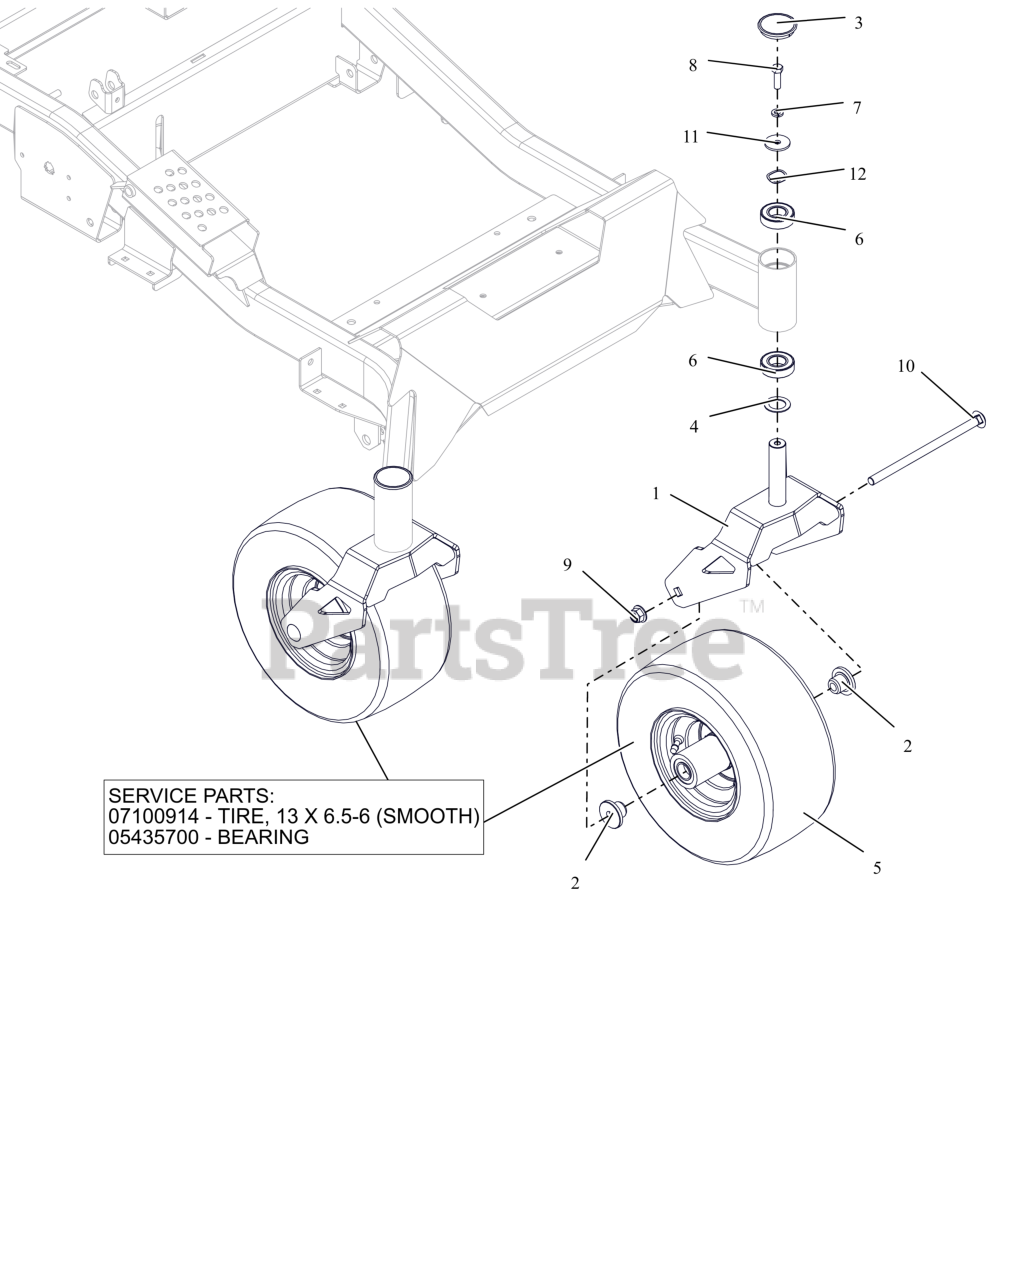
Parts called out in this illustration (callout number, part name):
1	WLDMT, HD CASTER FORK
2	SPACER, FRONT WHEEL
3	CAP, DUST
4	WSHR-HRD-THRS 1.007X1.542X.062
5	ASM, WHL/TIRE 13X6.50-6
5	TIRE, 13X6.50-6 SMOOTH
5	BRG, 25MM ID X 52MM OD X 15MM
6	BRG,BALL 1.00X2.00X.563(1641)
7	WSHR, LK-HVY .375X.115 ZCC
8	BLT, HEX .38-16X1.25 G5 ZCC
9	NUT,NYL-FLG .50-13 GF ZCC
10	BLT, RHSN .50-13X9.00 G5 ZCC
11	WSHR, FLT .380X1.50X.125 ZCC
12	WSHR-WAVE 1.0X1.25X.028 .145FH
